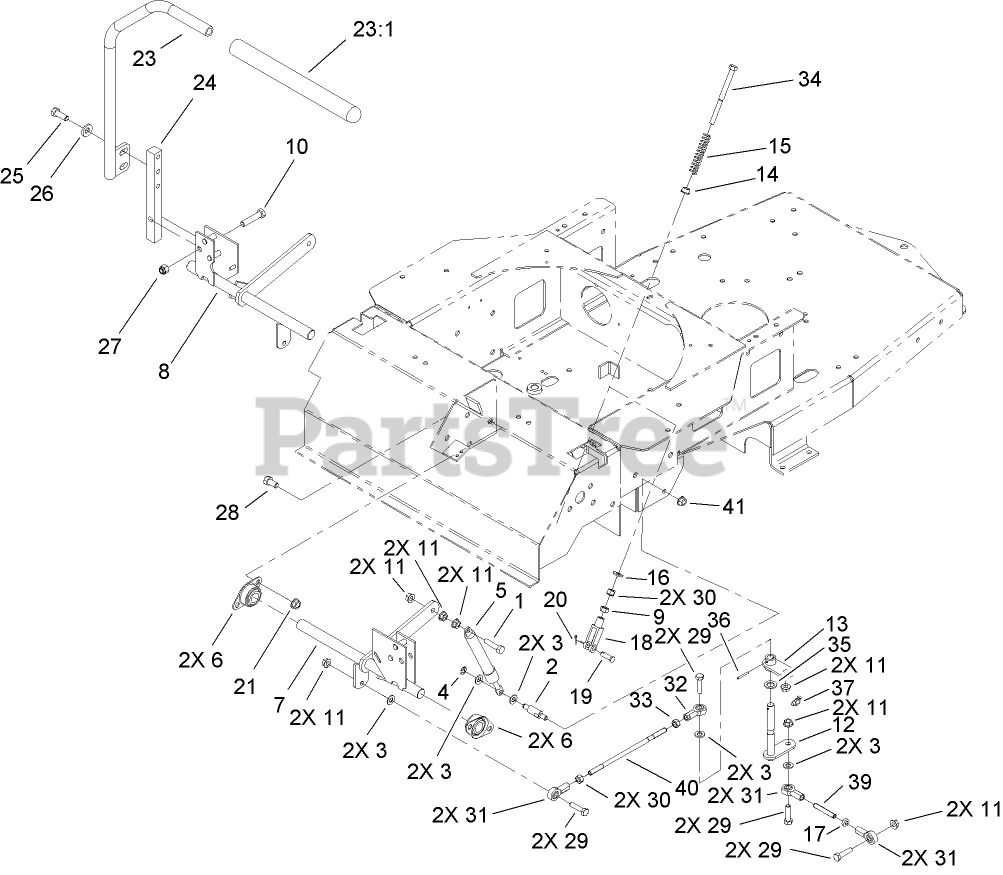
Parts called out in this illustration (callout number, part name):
1	SCREW-HH
2	PIN-DAMPER
3	WASHER-PLAIN
4	RING-RETAINING, EXT
6	BEARING-FLANGE, SIDE
7	BRACKET-MOTION CONTROL, LH
8	BRACKET-MOTION CONTROL, RH
9	NUT-LOCK
10	SCREW-HH
11	NUT-HF
12	PIVOT ASM
13	PIVOT PLATE ASM
14	BUSHING-FLANGED
15	SPRING-RETURN, NEUTRAL
16	WASHER-FLAT
17	NUT-JAM
18	YOKE-ADJUSTABLE
19	PIN-CLEVIS
20	PIN-COTTER
21	NUT-HHF, WHIZ
23	RH LEVER ASM
23:1	GRIP-CONTROL, MOTION
24	ARM-SHAFT, CONTROL
25	SCREW-HH
26	WASHER-BELLEVILLE
27	NUT-LOCK, NI
28	SCREW-HH
29	SCREW-HH
30	NUT-HEX
31	BALLJOINT-RH
32	BALLJOINT-LH
34	BOLT-RETURN, NEUTRAL
35	WASHER
36	PIN-ROLL
37	FITTING-LUBE, 45 DEG
39	LINKAGE-LOWER, LH
40	LINKAGE-UPPER
41	NUT-HF
